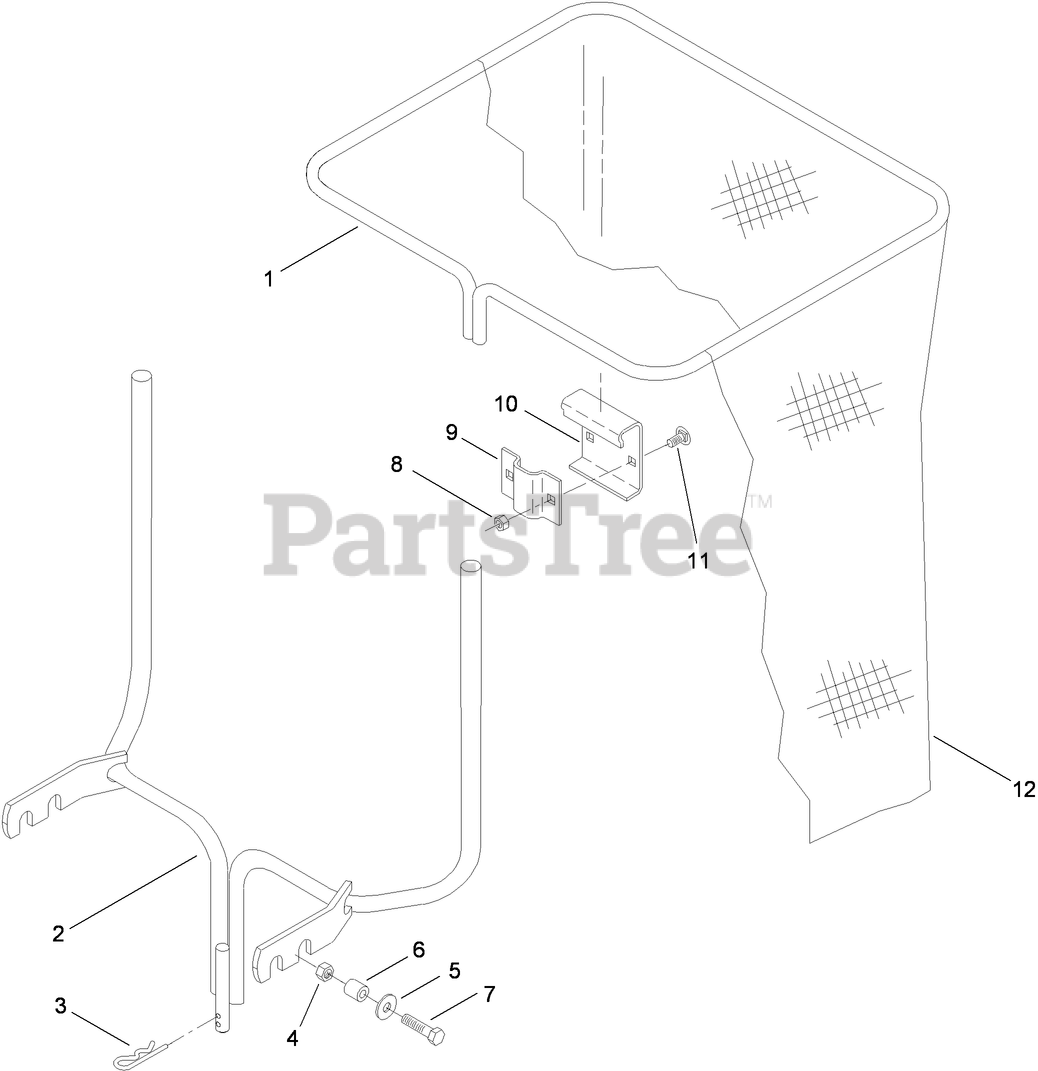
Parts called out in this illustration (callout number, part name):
1	FRAME-BAG
2	BRACKET-BAGGER ASM
3	PIN-COTTER, HAIR
4	NUT-LOCK, NI
6	SPACER
7	SCREW-HH
8	NUT-LOCK, NI
10	HANGER-BAG
11	BOLT-CARR
12	BAG-DEPTH
